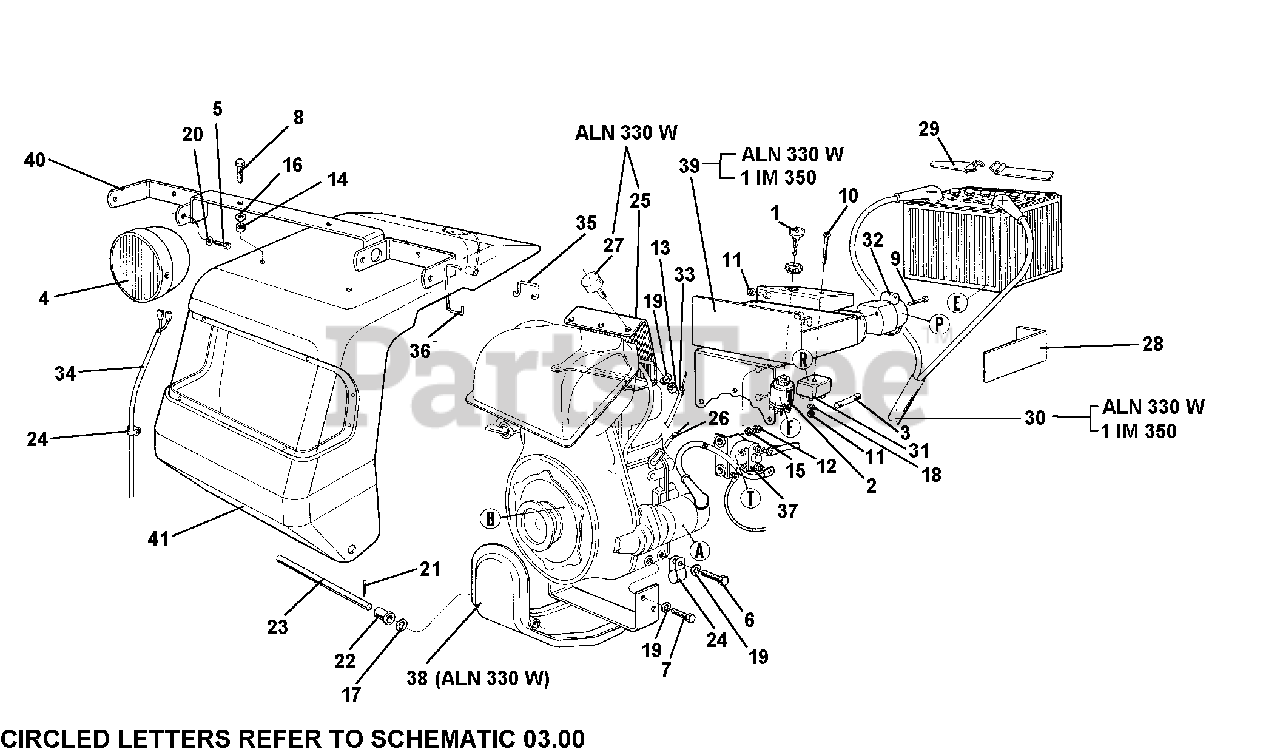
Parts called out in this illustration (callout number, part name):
3	FUSE 6 X 25 25A
5	SCREW TE M6 X 14
6	SCREW TE M8 X 12
7	SCREW M8 X 16
8	SCREW M8 X 25
9	SCREW TCCEI M4 X 30
10	SCREW TC M4 X 30 UNI 6107
14	NUT, SELF LOCKING M8
15	WASHER, FLAT 6.4
16	FLAT WASHER 9 X 24 UNI 6593
17	FLAT WASHER 10.5 X 21
18	LOCK WASHER B 4.3
19	WASHER, LOCK 8.4
20	WASHER, LOCK AZ 6.4 DIN 6798
21	PIN, COTTER A 3 X 20 UNI 1336
23	PIN, COUPLING
24	CLAMP ENGINE
25	CONNECT. UPPER ELECTRIC ST.
26	CABLE & SHEATH, ACCEL.LOMBAR
28	ANTISHOCK BAT
29	BATTERY STRAP
30	ELECTRIC START CABLES MC 715
32	7-POLE SOCKET
33	SHEATH CABLE
34	COVER CABLES
35	ELECTRIC STARTER HOOK
37	BOSCH RELAY 0332002160
38	HOOD LOWER COUPLING
39	SUPPORT BATTERY
40	LIGHT SUPPORT
